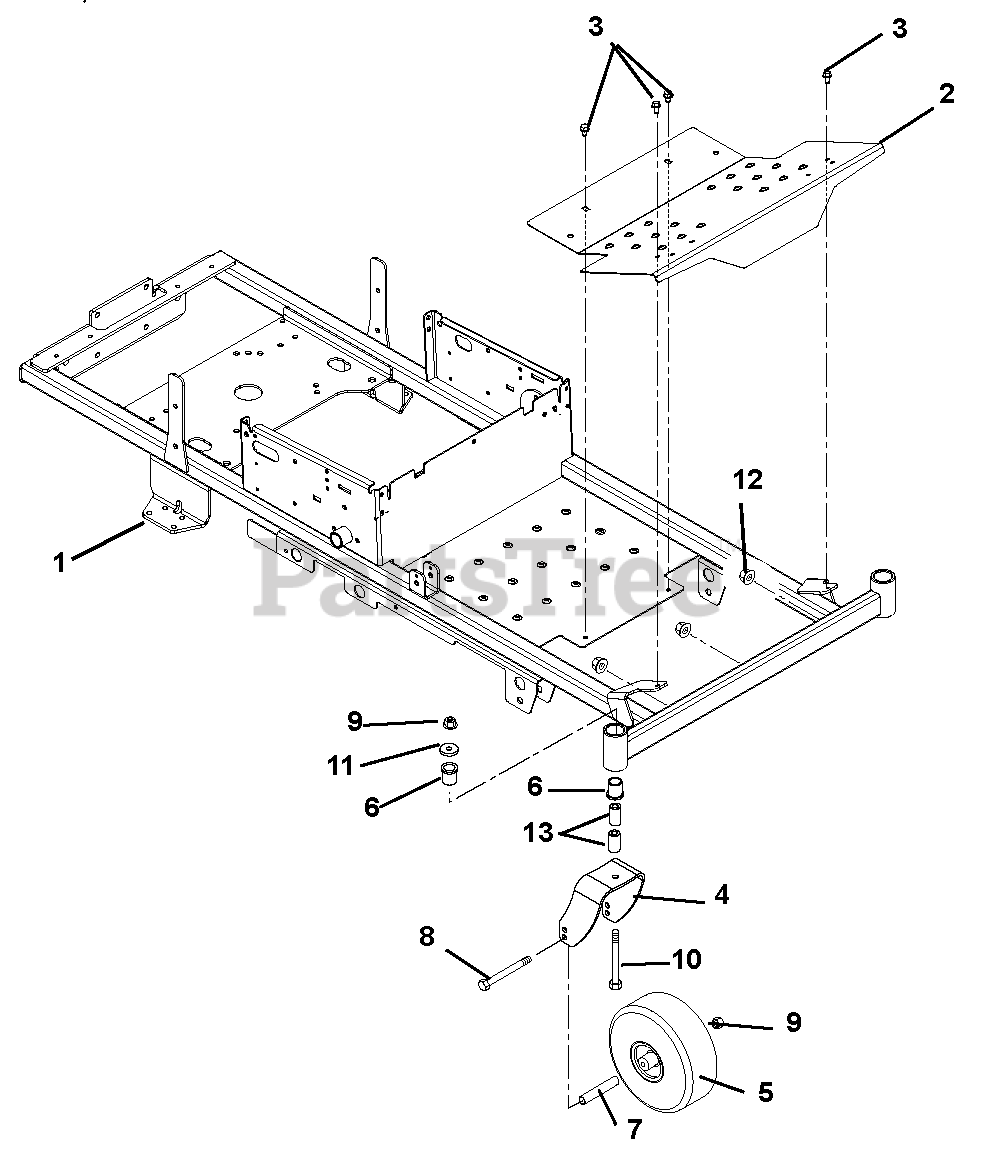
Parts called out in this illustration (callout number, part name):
1	Weldment, Frame
2	Footplate
3	Screw, Tapping .31-18 x .50
4	Fork, Caster
5	Wheel/Tire Assembly, 11.0 x 4.0 x 5.0, Monitor
6	Bushing, Flange 1.00 x 1.25 x 1.50 x 1.50
7	Spacer, Wheel
8	Bolt, Hex .50-13 x 6.50 Grade 5
9	Nut, .50-13 Nyloc Flange
10	Bolt, Hex .50-13 x 5.00 Grade 5
11	Washer, Flat Steel .511 x 1.441 x .125
12	Nut, Nyloc Flange .62-11
13	Spacer, Caster
